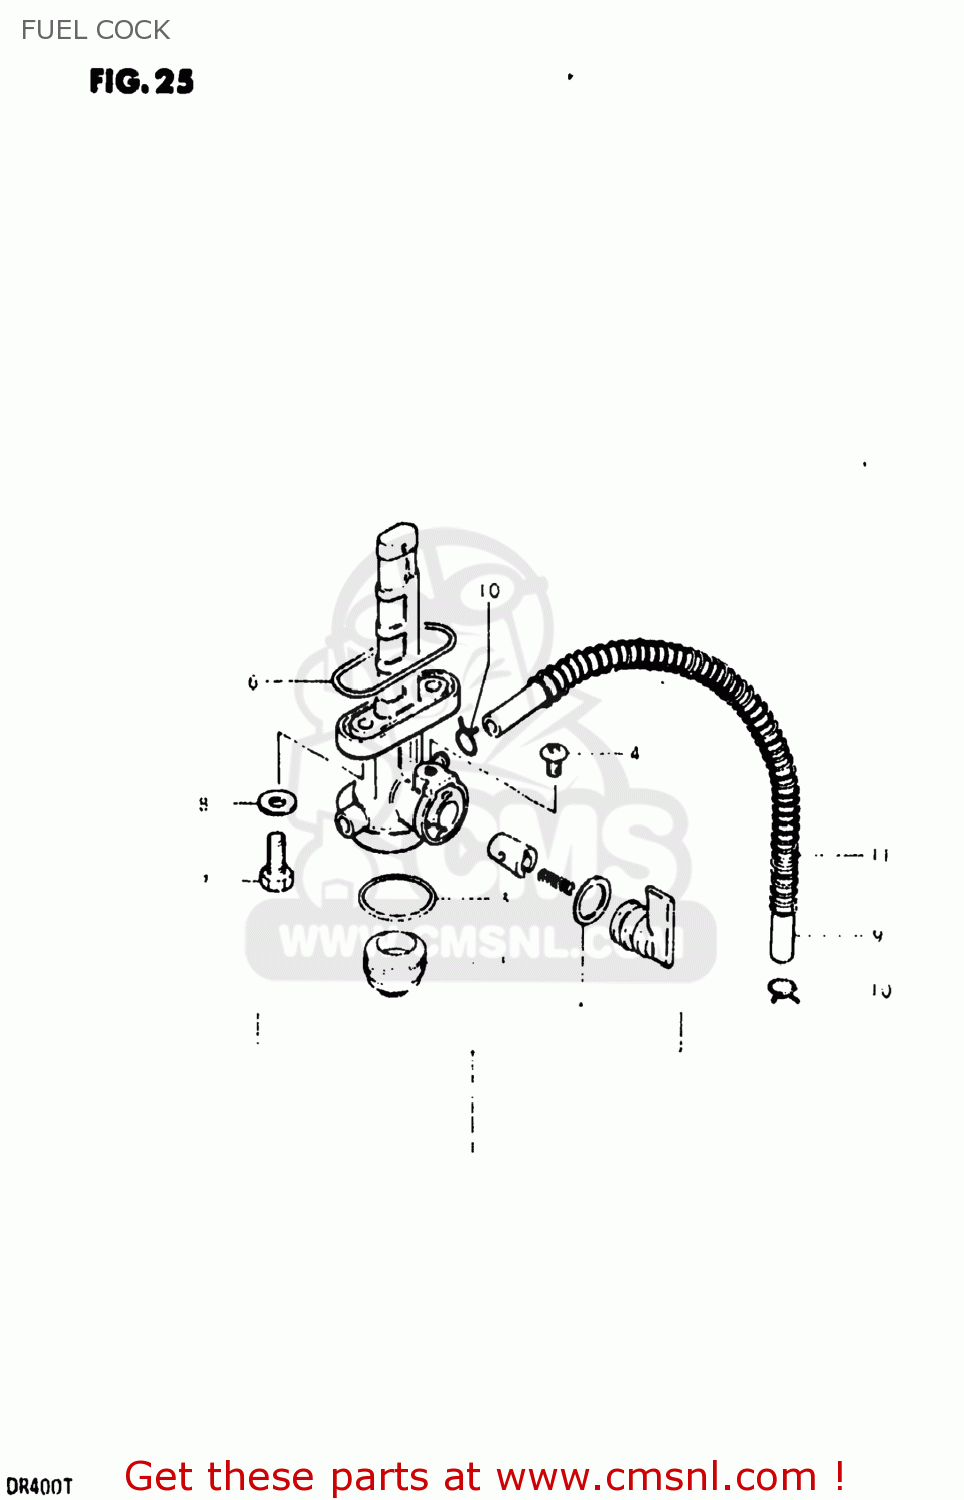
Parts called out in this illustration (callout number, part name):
1	COCK ASSEMBLY,FUEL
2	O-RING
3	GASKET,FILTER (NAS)
4	SCREW,FUEL COCK LEVER
5	CUP,STRAINER
6	O RING,FUEL COCK
7	BOLT(6X20)
8	GASKET
9	HOSE
10	CLIP
11	SPRING
